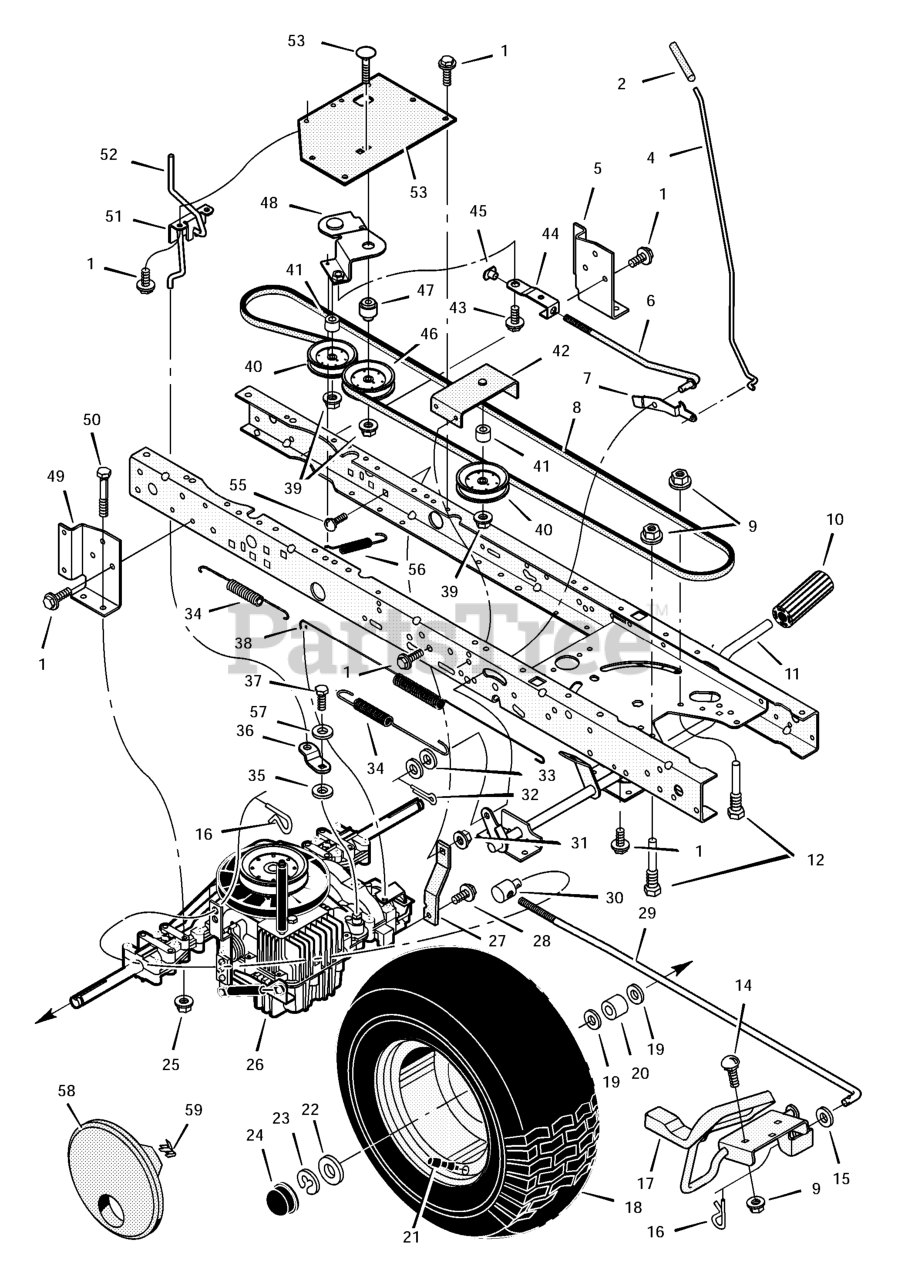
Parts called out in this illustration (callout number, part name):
2	Grip, Parking Brake
4	Rod, Parking Brake
5	Bracket, Left Transaxle
6	Rod, Clutch
7	Latch, Parking Brake
8	V-Belt, Drive
9	Nut, Flange
10	Pedal, Brake/Clutch
11	Assembly, Brake Pedal
12	Screw, Guide
14	Bolt, Carriage
16	Pin, Hair
17	Pedal Assembly, Hydro
18	Wheel & Tire Ass'y, Rear
20	Spacer
21	Stem, Valve
24	Cover, Dust
25	Nut, Centerlock
26	Transaxle **
27	Strap, Torque
29	Rod, Control
30	NUT, Adjusting, 1/2-13
31	Nut, Centerlock
32	Pin, Cotter
34	Spring, Extension
36	ARM, Disconnect
37	Capscrew
38	Spring, Brake
39	Locknut, Flange
40	Pulley, Idler
42	Bracket, Idler Assembly
43	Bolt, Shoulder
44	Link, Clutch
45	Nut, Tee
46	Pulley, Idler
47	Bushing, Pivot
48	Arm Assembly, Idler
49	Bracket, Right Transaxle
50	Bolt, Hex
51	Bracket, Disconnect
52	Rod, Disconnect
53	Bracket, Idler Pivot
54	Bolt, Carriage
55	Bolt, Carriage
56	Spring, Clutch
58	Cap, Hub
59	Retainer
